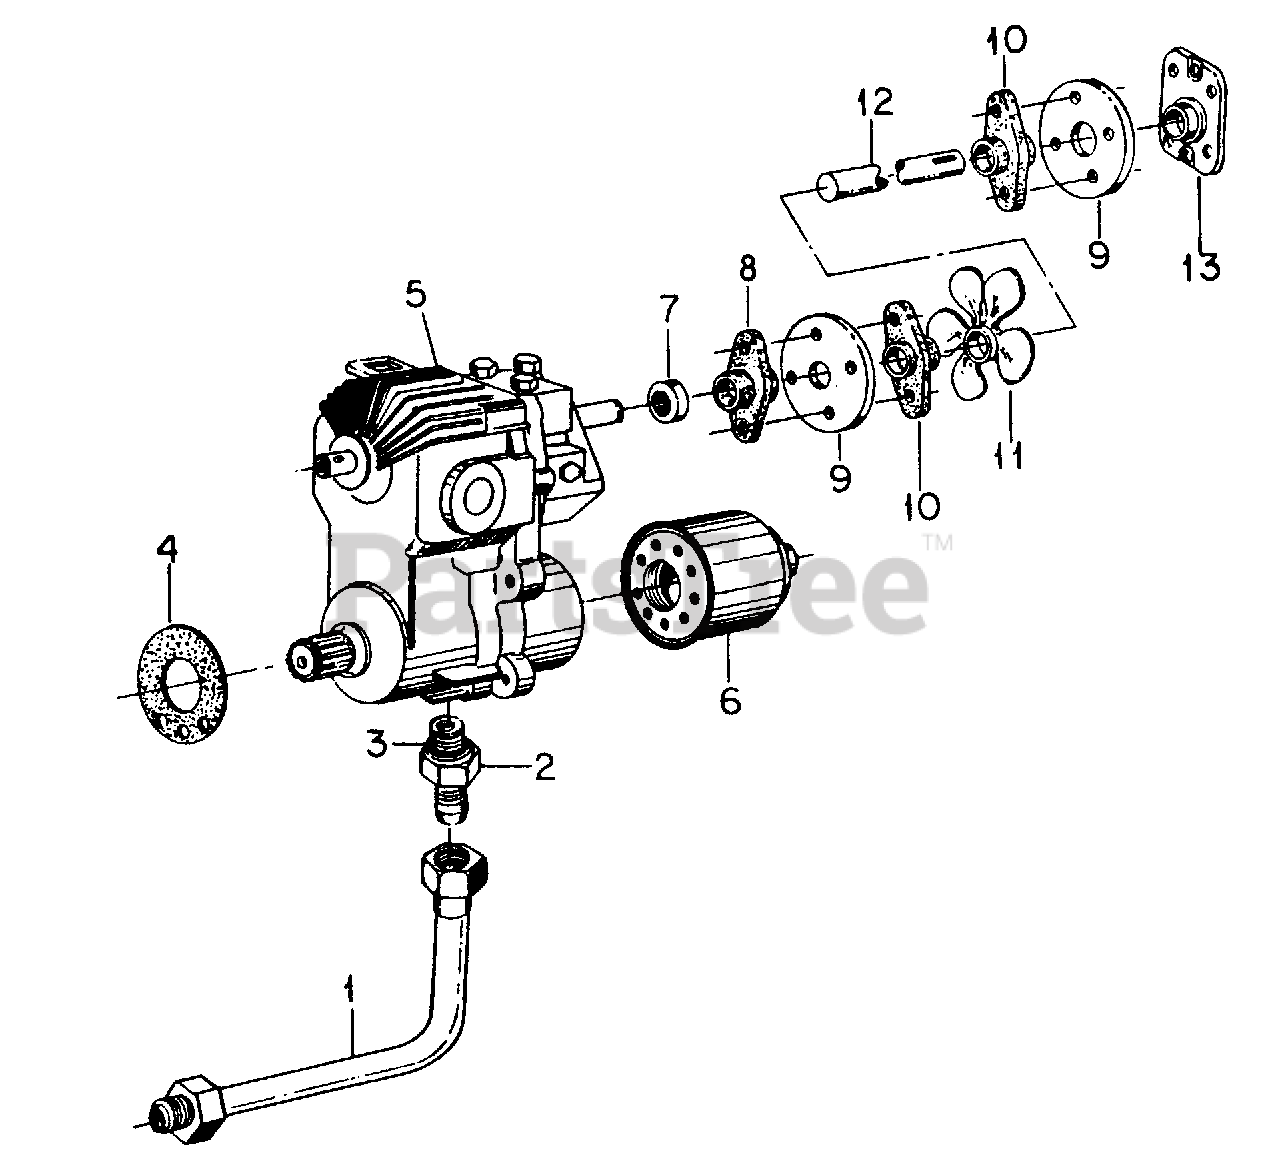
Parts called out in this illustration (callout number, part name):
1	Tube Assy, Transmission
2	Connector, 5/8 C-Z Hyd Fld Short Swivel
3	O-Ring, 5/8 OD Tube Class 6
4	Gasket, Front
5	Transmission, Hydrostatic
6	Filter, Oil
7	Bushing, Self Aligning Ball
8	Coupler, Drive Shaft
9	Disc, Flexible
10	Arm, Coupling
11	Fan, Cooling
12	Shaft, Drive
13	Flange, Drive Shaft
